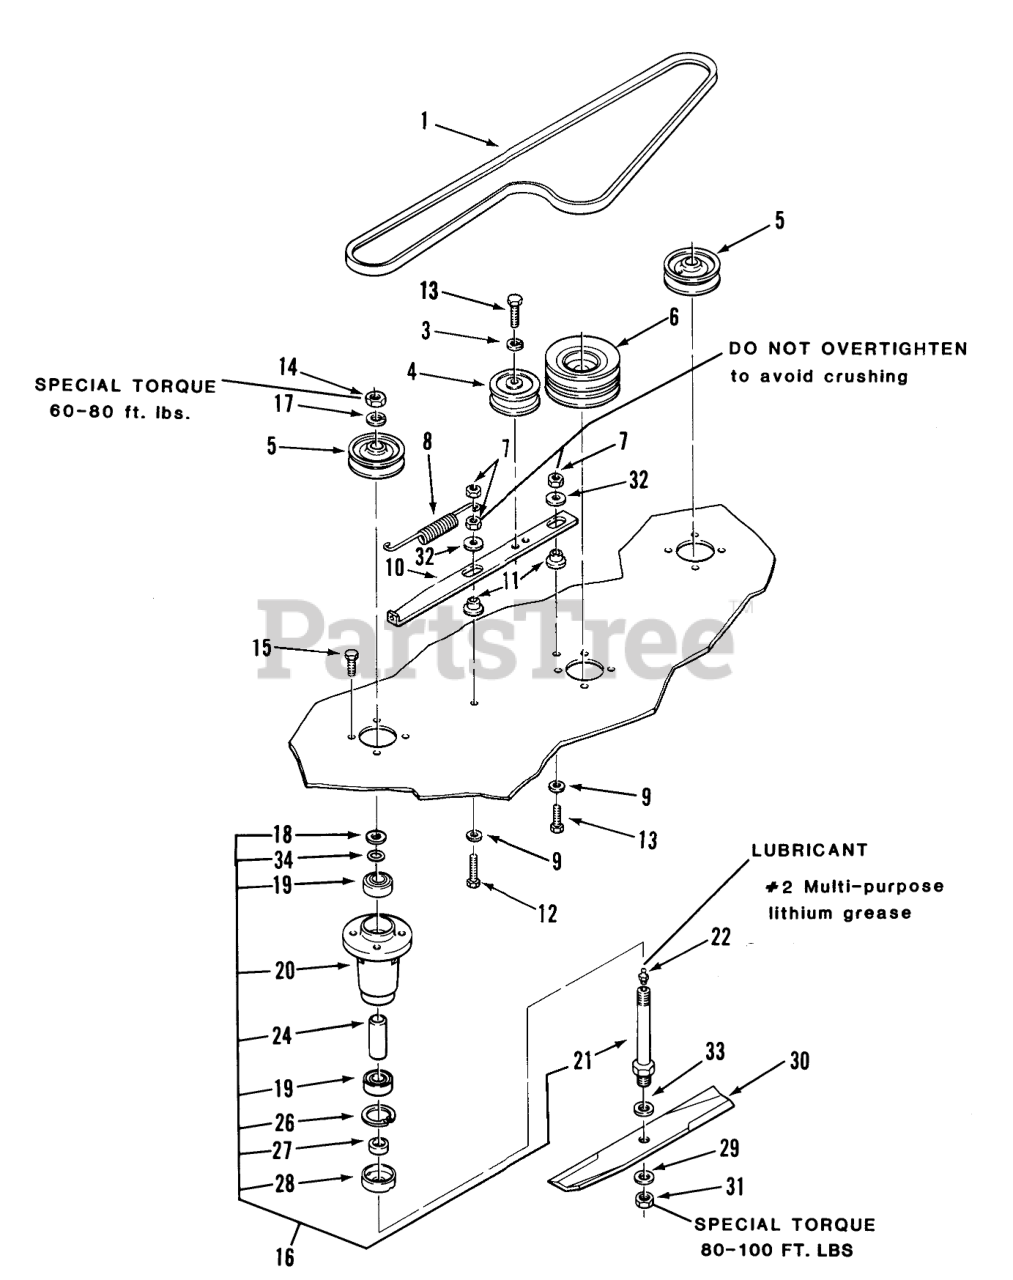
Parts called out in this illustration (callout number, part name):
1	V-BELT
3	LOCKWASHER
4	PULLEY-IDLER
5	PULLEY
6	PULLEY CENTER
7	NUT
8	SPRING-EXTENSION
9	WASHER
10	BAR-IDLER SUPPORT
11	SPACER-BUSHING
12	Bolt
13	Bolt
14	Jam Nut
15	Bolt
16	ASSY 36" SPINDLE
17	Lockwasher
18	Washer
19	BEARING-BALL
20	HOUSING-SPINDLE
21	SHAFT-SPINDLE
22	Zerk
26	Ring-Snap
27	SPACER-BLADE
28	CUP-SPINDLE
29	Washer
30	S/A BLADE KIT
31	Nut-Jam
32	WASHER
33	Washer
34	O RING
